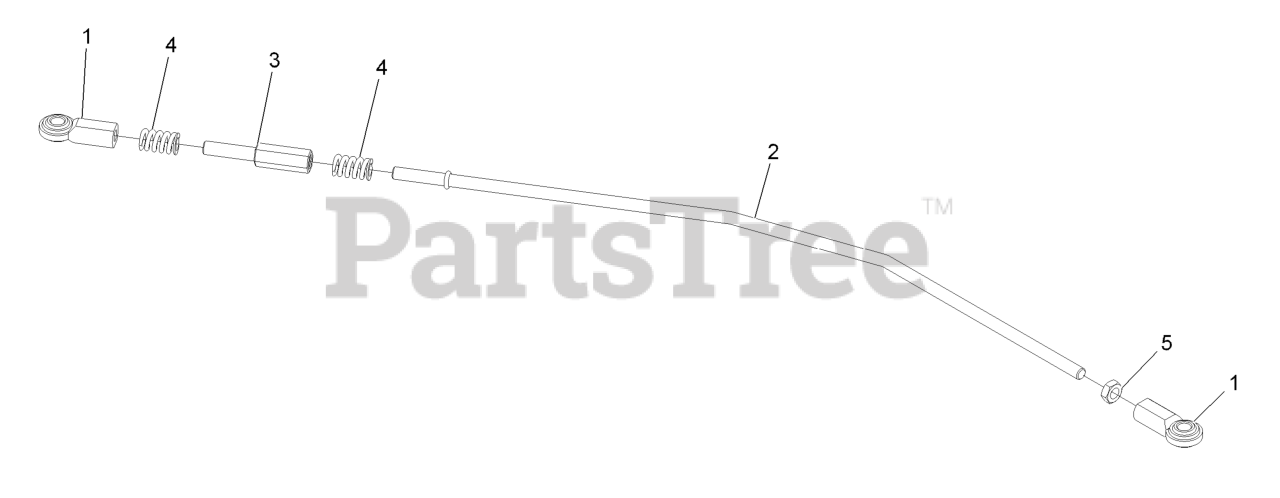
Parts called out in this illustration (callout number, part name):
1	JOINT-BALL, END
2	LINK-LOWER,MOTION CONTROL
3	ROD-ADJUSTMENT
4	SPRING-COMPRESSION
5	NUT-HJ
